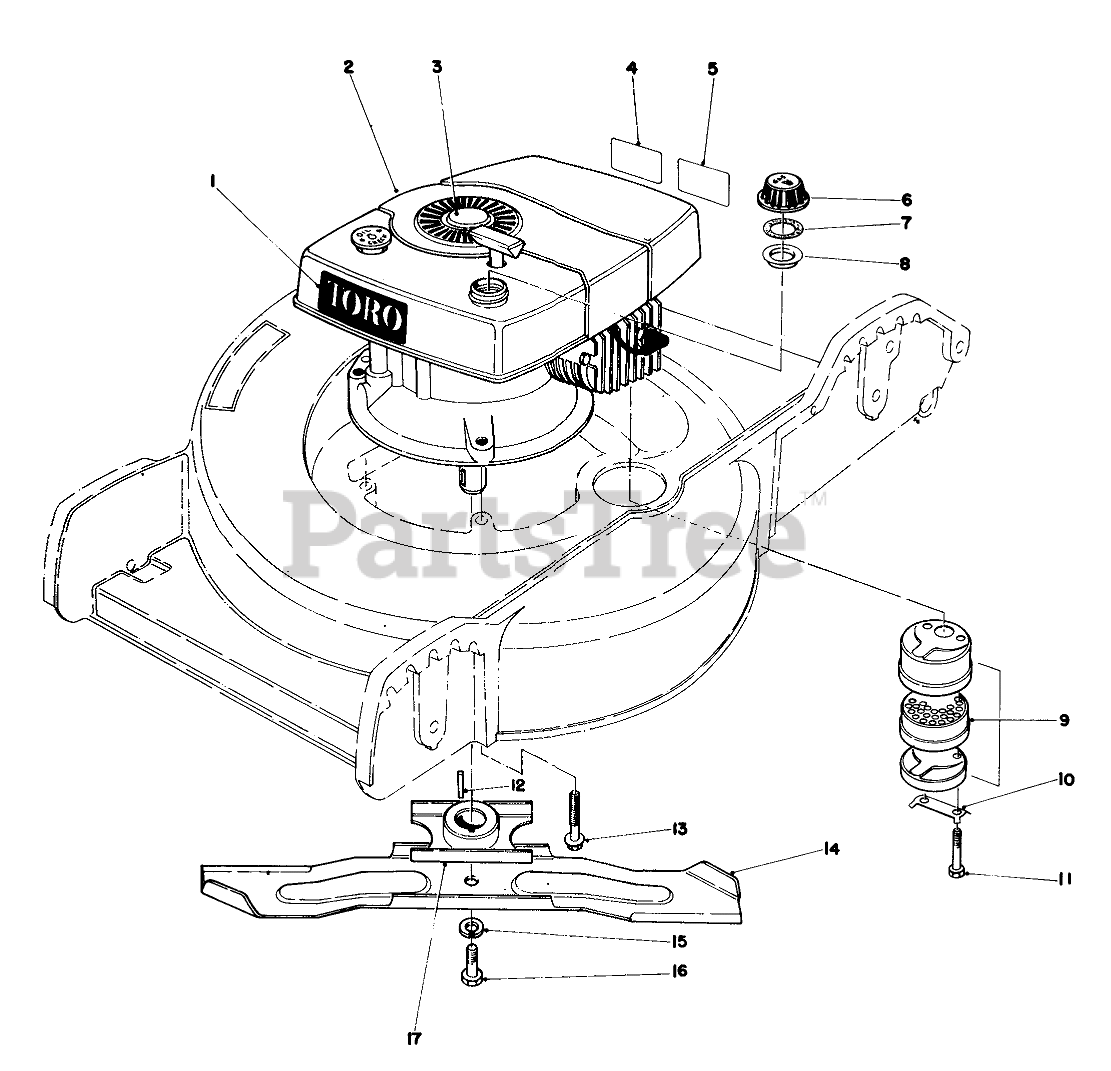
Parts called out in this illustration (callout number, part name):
1	Decal-Toro
2	Engine
3	Plug Button
4	Decal-Maintenance
5	Decal-Maintenance
6	Gas Cap (Incl. Ref. #7 & 8)
7	GASKET
8	GAS CAP BAFFLE
9	Muffler Assy. (Incl. Ref. #10 & 11)
10	CLIP - LOCKING
11	SCREW-HH
12	KEY-SQUARE
13	3/8-16 X 2 CAPSCREW
14	Blade
15	WASHER-LOCK
16	SPECIAL SCREW
17	Blade Retailer
